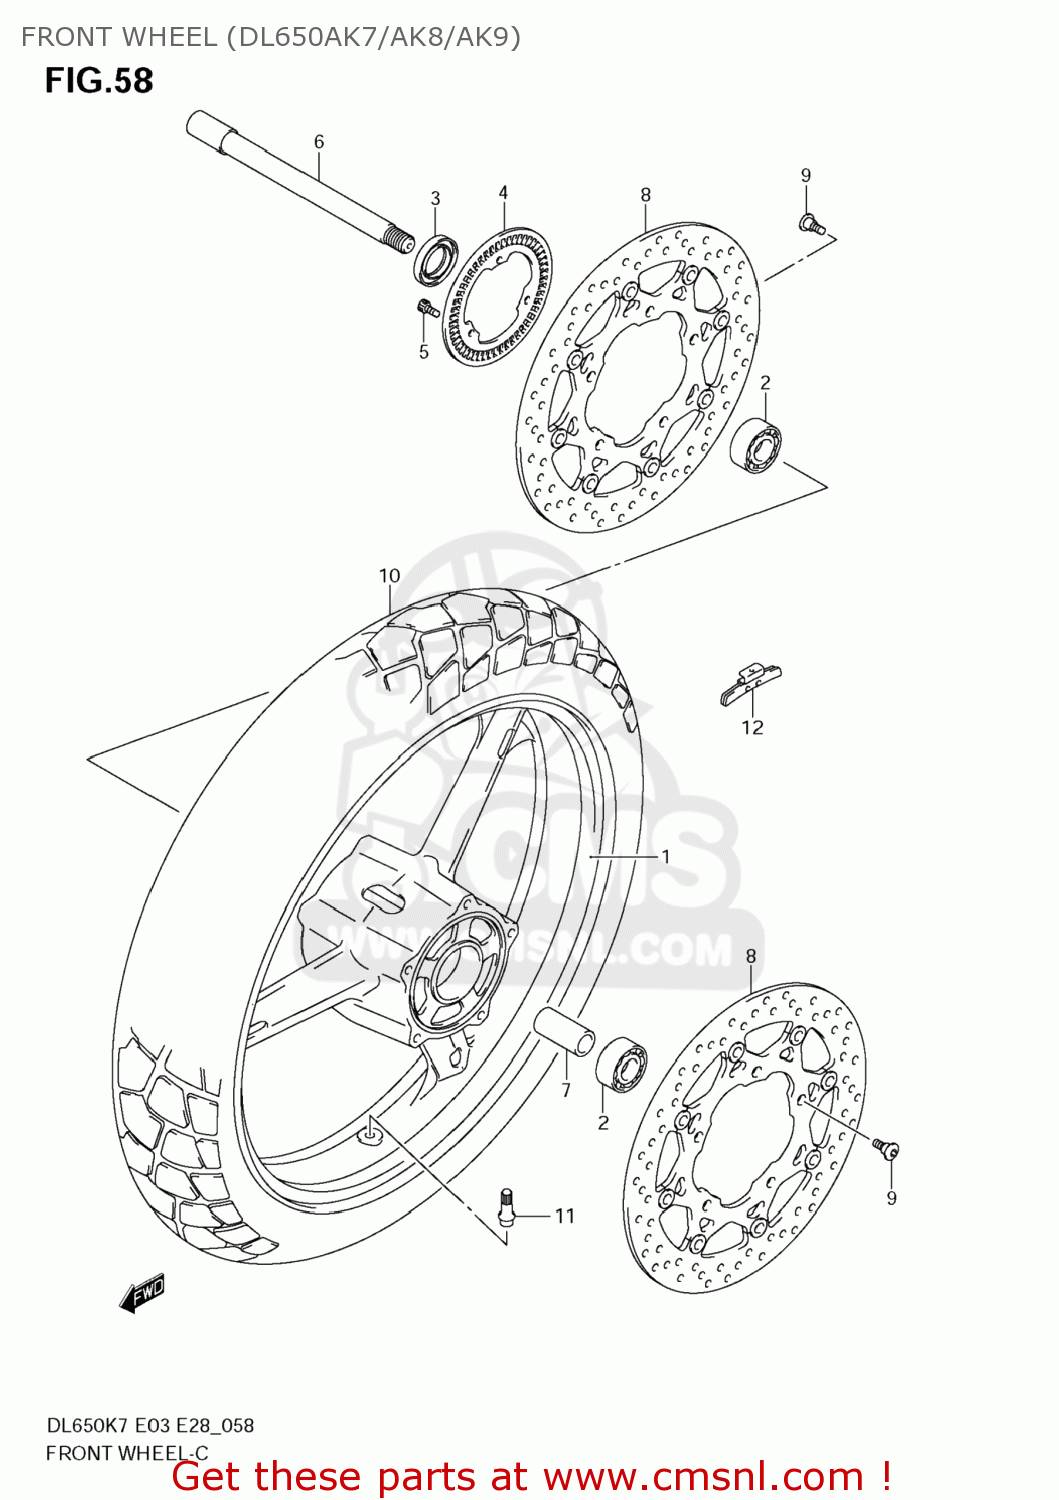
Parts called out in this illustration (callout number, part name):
1	WHEEL,FR(19M/C
2	BEARING
3	SEAL,OIL(24X40X7)
4	RING,SPEED SENSOR FR(50T)
5	BOLT
6	AXLE,FR
7	SPACER(17.5X25X88)
8	DISC,FRONT BRA
9	BOLT(8X21)
10	TIRE,FRONT,110
11	VALVE ASSY,WHEEL RIM(TR412)
12	WEIGHT,WHEEL BALANCE 10G
